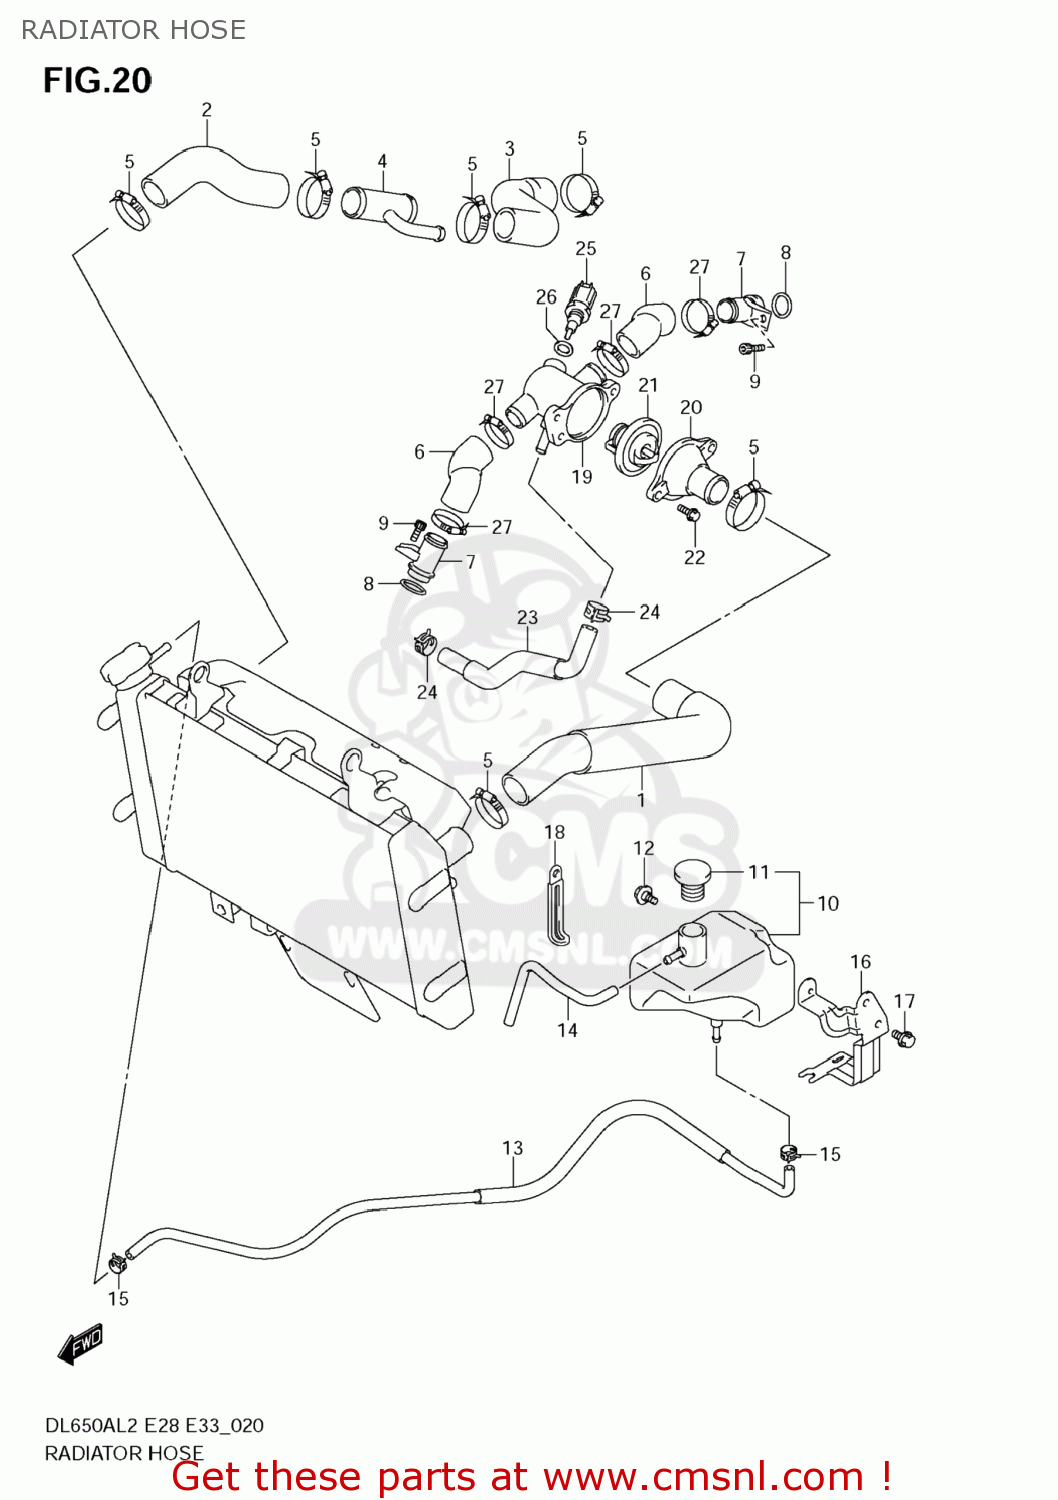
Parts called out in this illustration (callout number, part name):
1	HOSE,RADIATOR INLET
2	HOSE,RADIATOR OUTLET NO.1
3	HOSE,RADIATOR OUTLET NO.2
4	UNION,WATER HOSE THREE WAY
5	CLAMP
6	HOSE,CONNECTOR INLET
7	UNION,CONNECTOR HOSE
8	O RING(D:3.2,ID:17.8)
9	BOLT
10	TANK ASSY,RESERVOIR
11	CAP,RESERVOIR TANK
12	BOLT(6X12)
13	HOSE SET,RESERVOIR TANK INLET
14	HOSE,RESERVOIR TANK OVFL
15	CLIP
16	BRACKET,RESERVOIR TANK
17	BOLT
18	CLAMP(L:45)
19	CONNECTOR,THERMOSTAT INLET
20	CAP,THERMOSTAT CONNECTOR
21	THERMOSTAT,WATER
22	BOLT
23	HOSE,CONNECTOR TO WATER PUMP
24	CLAMP
25	SENSOR,TEMP
26	GASKET(12X17X1) (NAS)
27	CLAMP
